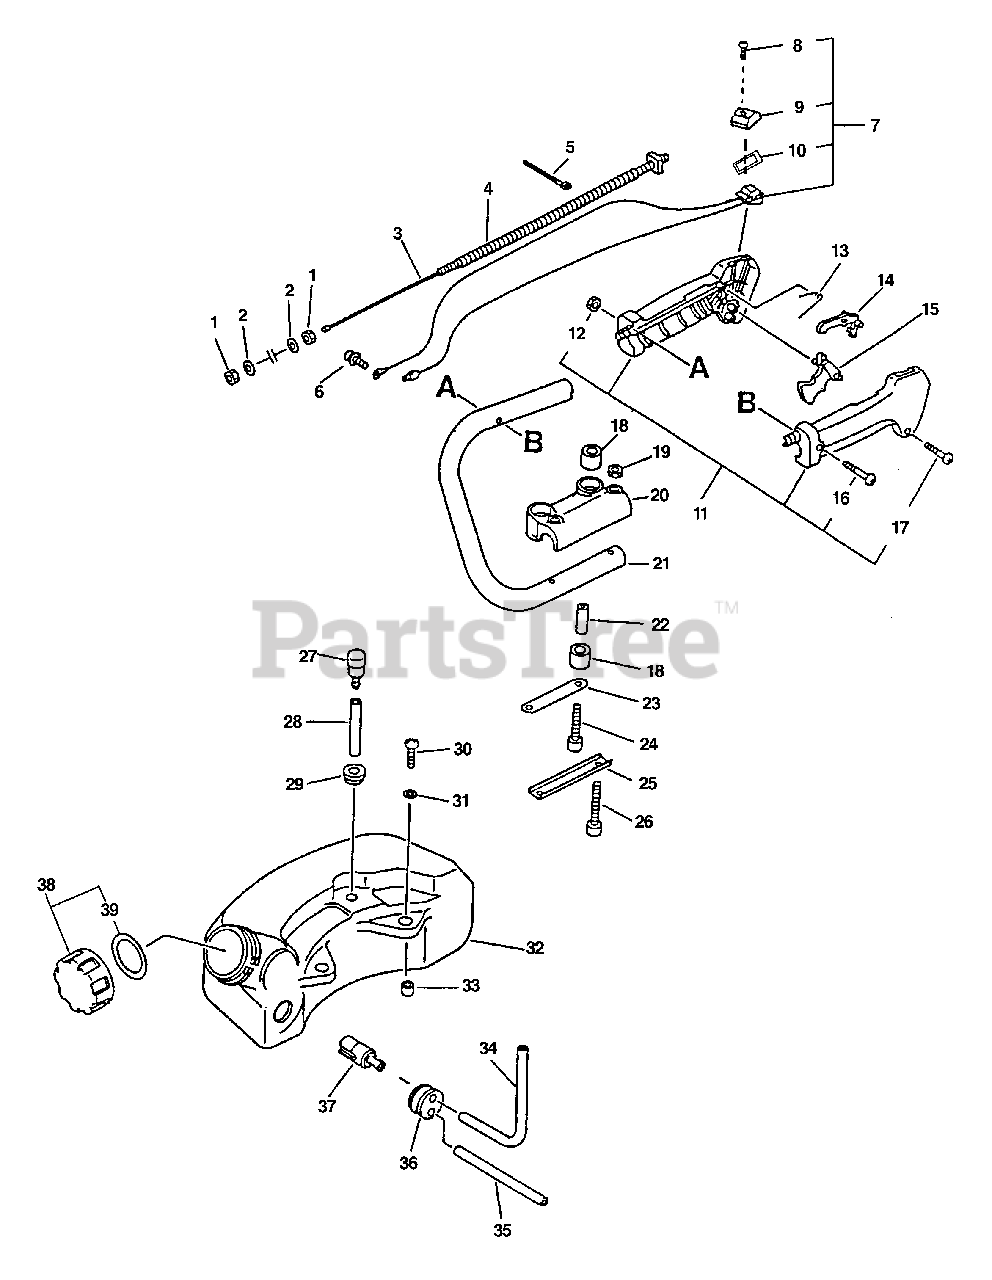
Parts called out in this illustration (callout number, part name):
2	WASHER - 6
3	CABLE, THROTTLE
5	TIE, CABLE
6	SCREW - 5X10
7	IGNITION SWITCH ASSY
8	SCREW - 3X10
9	KNOB, SWITCH - ORANGE
10	COVER, SWITCH - STOP
11	THROTTLE CONTROL ASSY
13	SPRING, LOCKOUT LEVER
14	LOCKOUT, THROTTLE
15	TRIGGER, THROTTLE
16	SCREW - 5X30
17	SCREW - 3X25
19	LOCKNUT - 5
20	SUPPORTER, HANDLE
21	HANDLE - REAR
22	SPACER
23	PLATE
24	SCREW - 5X40
25	BRACKET, HANDLE - LOWER
26	SCREW - 5X35
27	VENT, FUEL TANK
28	PIPE - 3X6X35 -- BLACK
29	GROMMET
30	SCREW - 5X16
31	WASHER - 5
32	TANK, FUEL
34	PIPE, FUEL - CORRUGATED
35	PIPE - 3X6X110 -- CLEAR
36	GROMMET
37	FILTER, FUEL
38	CAP ASSY
39	GASKET, CAP
